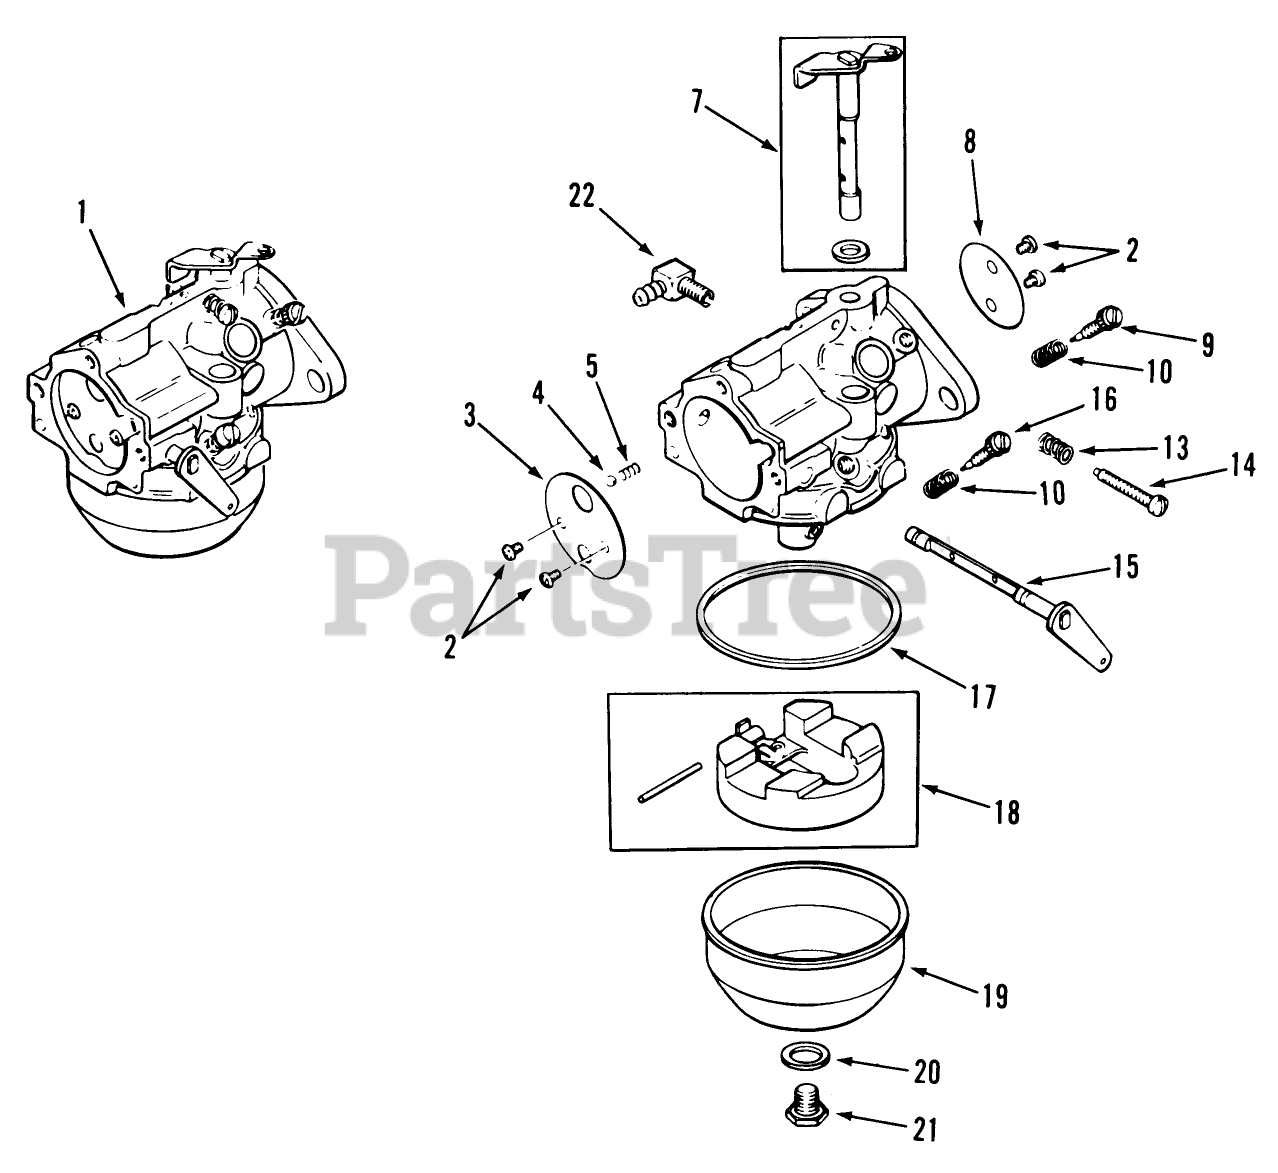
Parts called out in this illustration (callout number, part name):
1	KOHLER 47-853-20
2	KOHLER 25-086-27
3	KOHLER 47-146-08
4	KOHLER 25-194-01
5	KOHLER 25-089-03
7	KOHLER 457-144-21
8	KOHLER 25-146-02
9	KOHLER 25-368-01
10	KOHLER 25-089-02
13	KOHLER 25-089-04
14	KOHLER 25-086-26
15	KOHLER 47-090-38
16	Main-Needle
17	KOHLER 25-041-04
18	KOHLER 25-757-09
19	KOHLER 25-104-01
20	KOHLER 25-041-03
21	KOHLER 25-100-05
